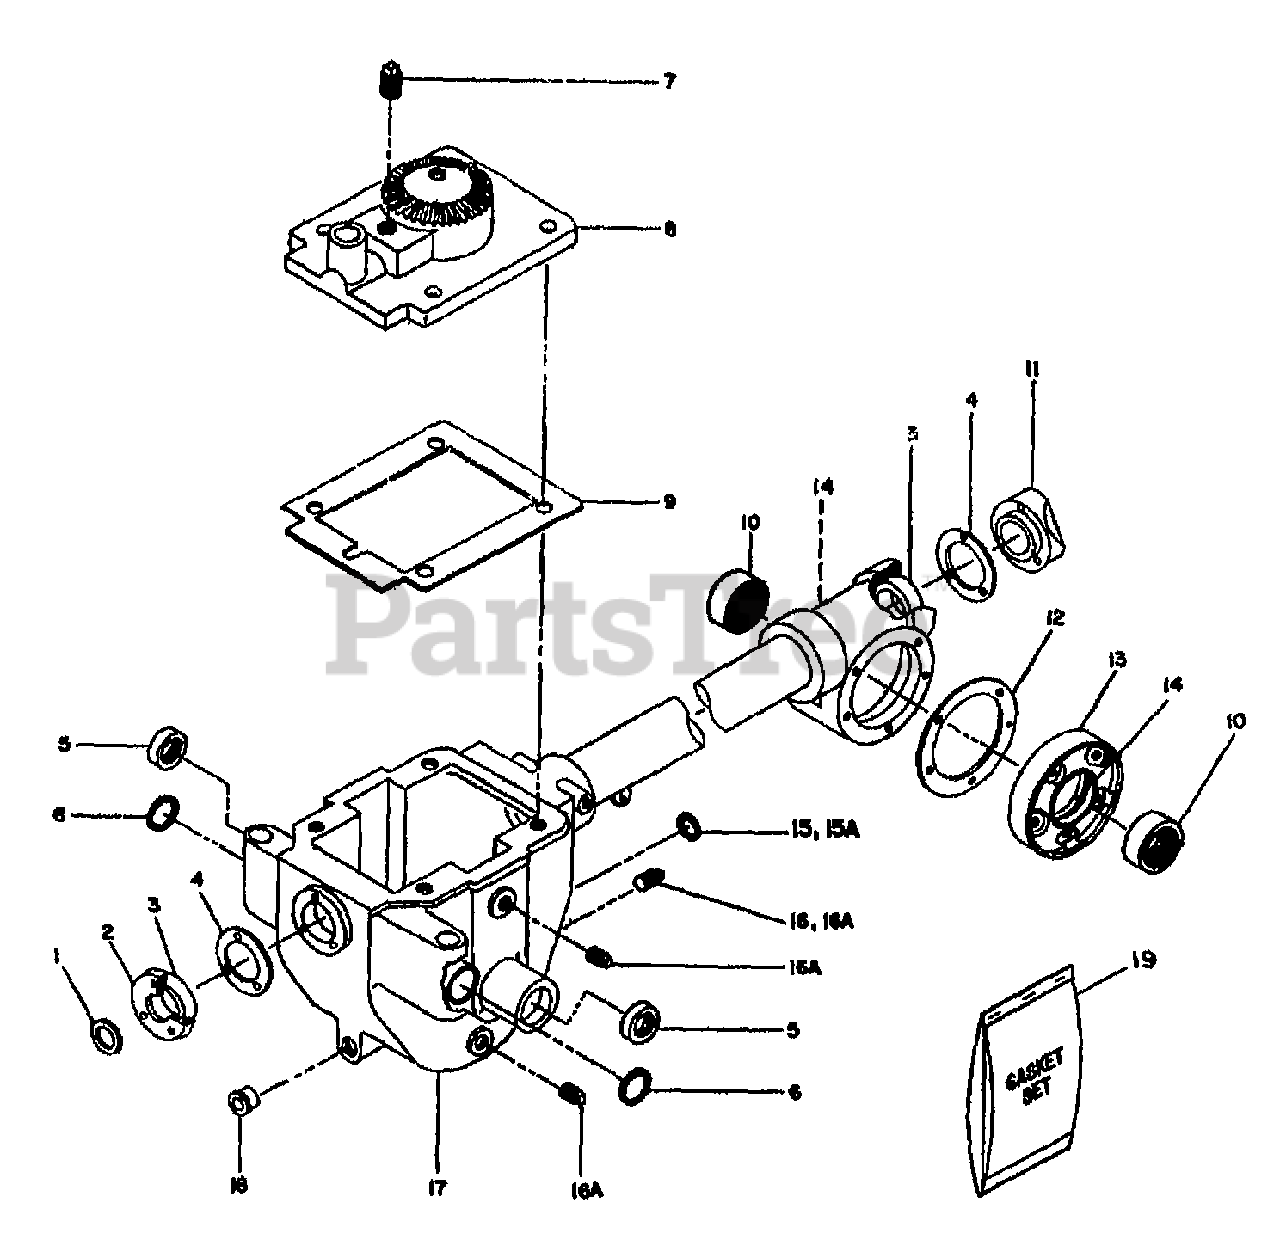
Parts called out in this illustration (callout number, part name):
1	SEAL-PINION SHAFT PT/85030/00
2	COVER-FRONT
3	KIT-BRG CONE&RACE-DRIVESHAFT
4	GASKET-BRG COVER
5	SEAL-OIL WHEELSHAFT
6	RING-O 1 ID
7	PLUG-PIPE 3/8 NPT
8	ASSM-COVER W/BOLT-HORSE
9	GASKET-TRANS COVER
10	SEAL-OIL TILLERSHAFT
11	CAP-REAR #1115
12	GASKET-TILLER COVER
13	COVER-W/SCRS(TLR) (9780)
14	KIT-TILLER GEAR & BRGS
15	SEAL-OIL ECCENTRIC
15A	RING-O .625 X .438
16	PLUG-PIPE 3/8 NPT
16A	PLUG-PIPE 1/4 NPT
17	CASE
18	PLUG-CAP (RED)
19	TRANS GASKET SET
